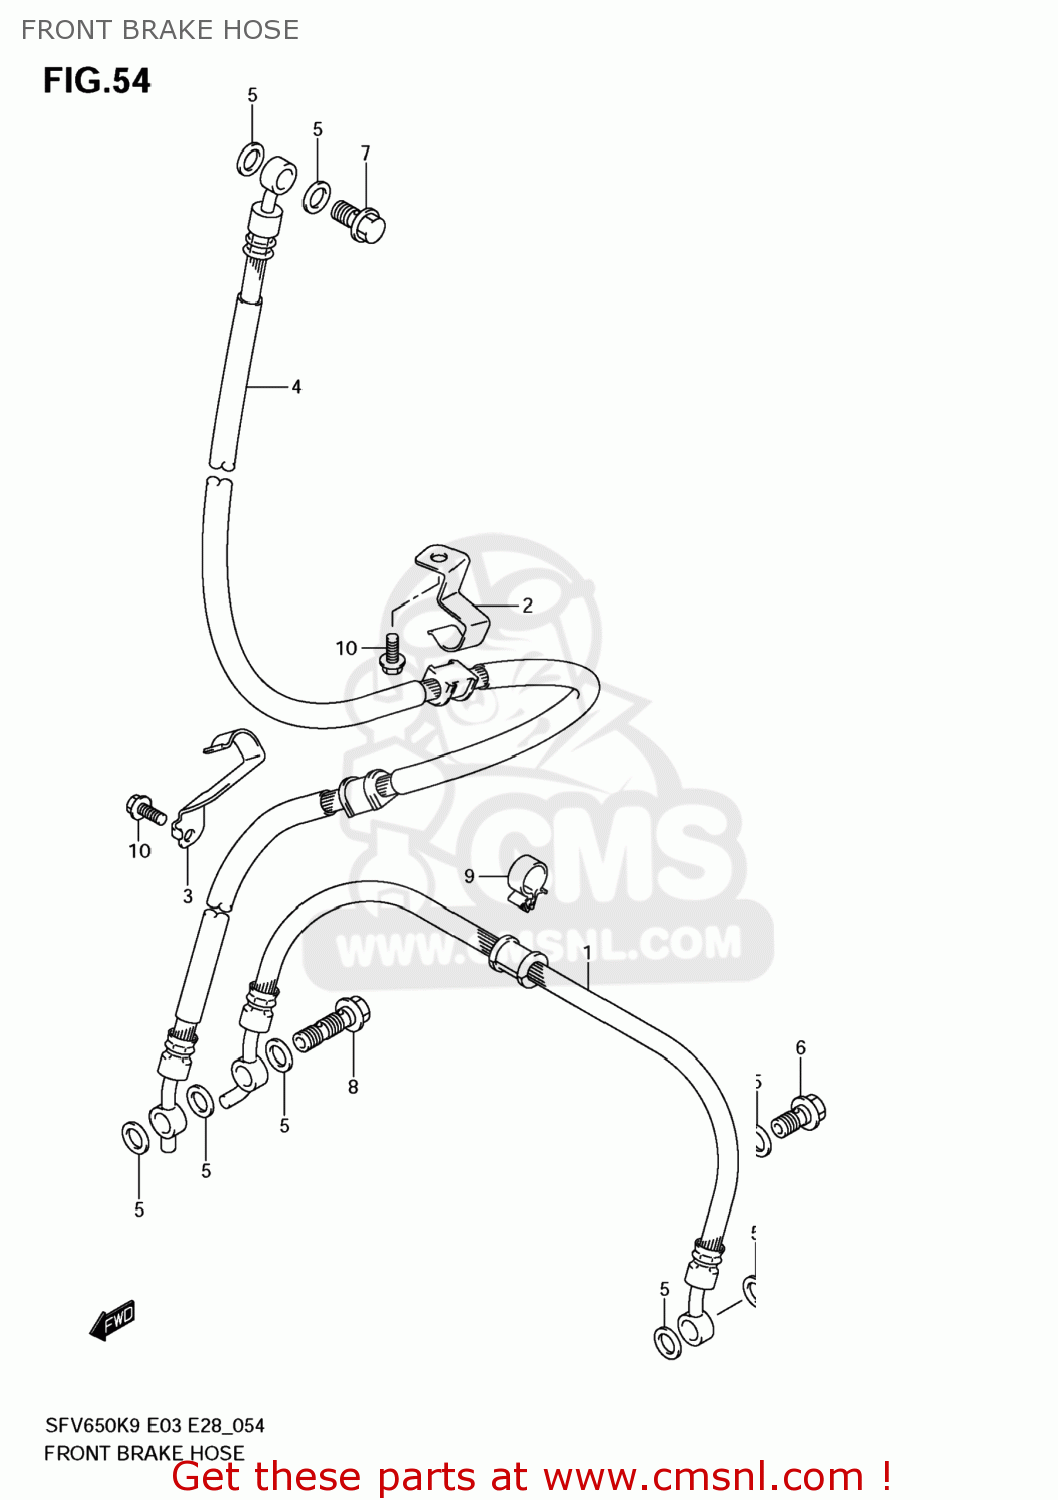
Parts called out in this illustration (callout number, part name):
1	HOSE,FR BRAKE NO.2
2	CLAMP,FR BRAKE HOSE NO.1
3	CLAMP,FR BRAKE HOSE NO.2
4	HOSE,FR BRAKE NO.1
5	WASHER(10X15X1.5)
6	BOLT UNION
7	BOLT UNION
8	BOLT UNION
9	CLAMP
10	BOLT
